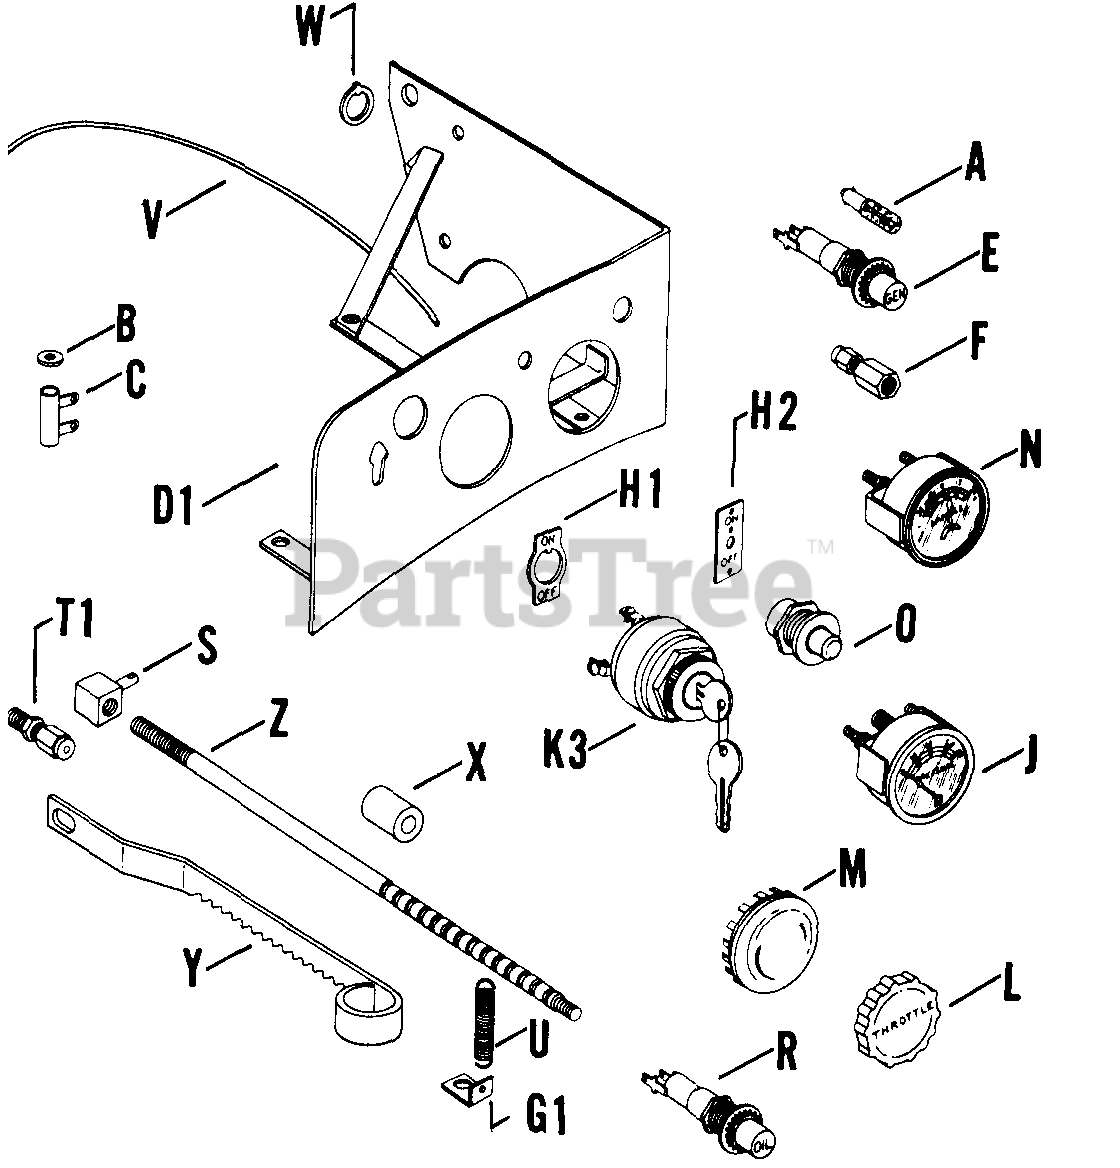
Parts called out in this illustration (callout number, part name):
H1	PLATE - DISCONTINUED
L	KNOB - DISCONTINUED
N	AMMETER - USE 277190
O	SWITCH - DISCONTINUED
S	BLOCK - (#DSC)
U	SPRING - (#DSC)
V	LINE - USE X-302-5-S
W	RING -DISCONTINUED
